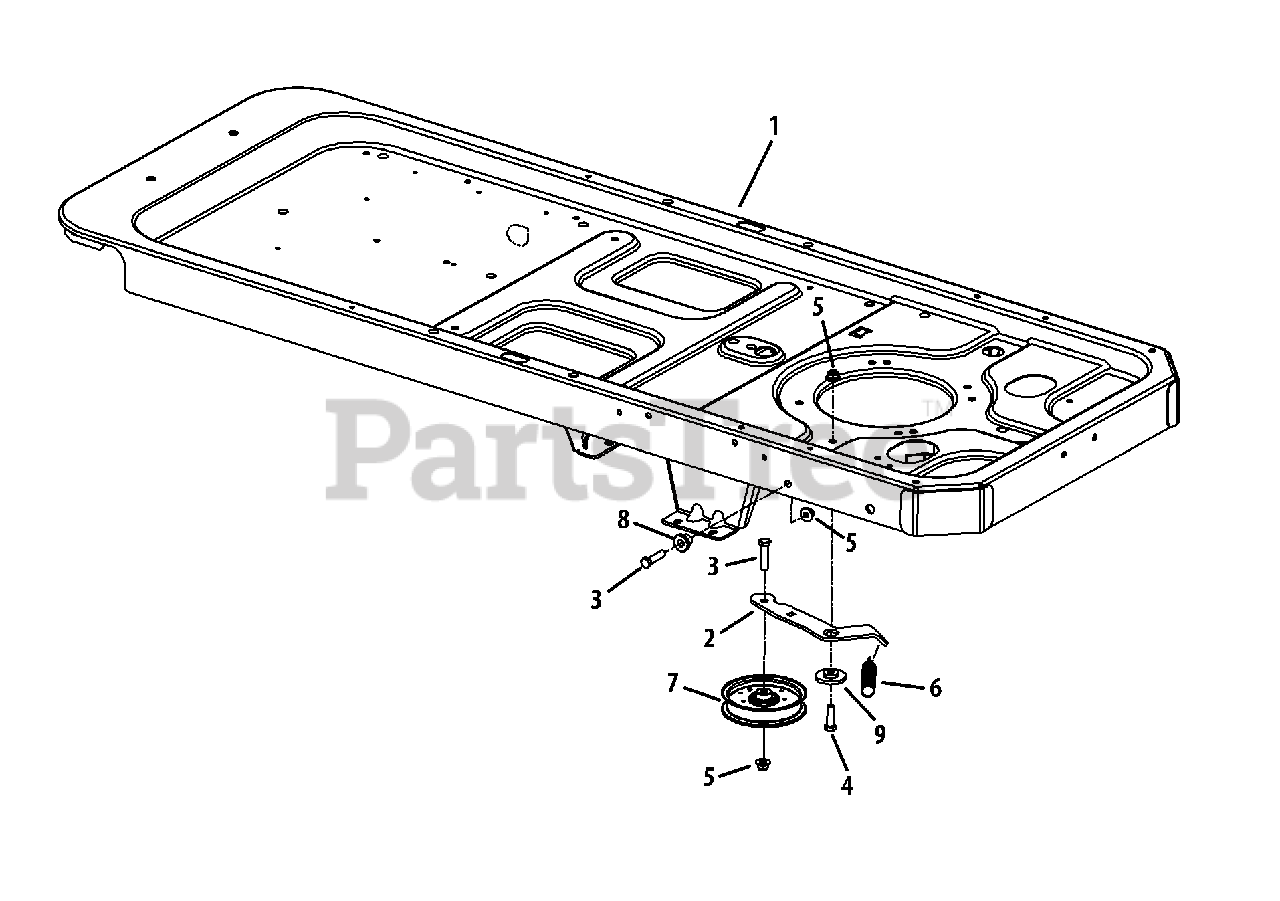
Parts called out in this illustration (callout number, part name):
1	Frame Assembly
3	Hex Screw, 3/8-16 x 1.5
4	Hex Screw, 3/8-16 x 1.25
5	Flange Nut, 3/8-16
6	Extension Spring, .75 x 5.06
7	Idler Pulley, 4.25 Dia.
8	Shoulder Spacer, .39 x 1.0 x .7
9	Shoulder Spacer, .884 x .19
